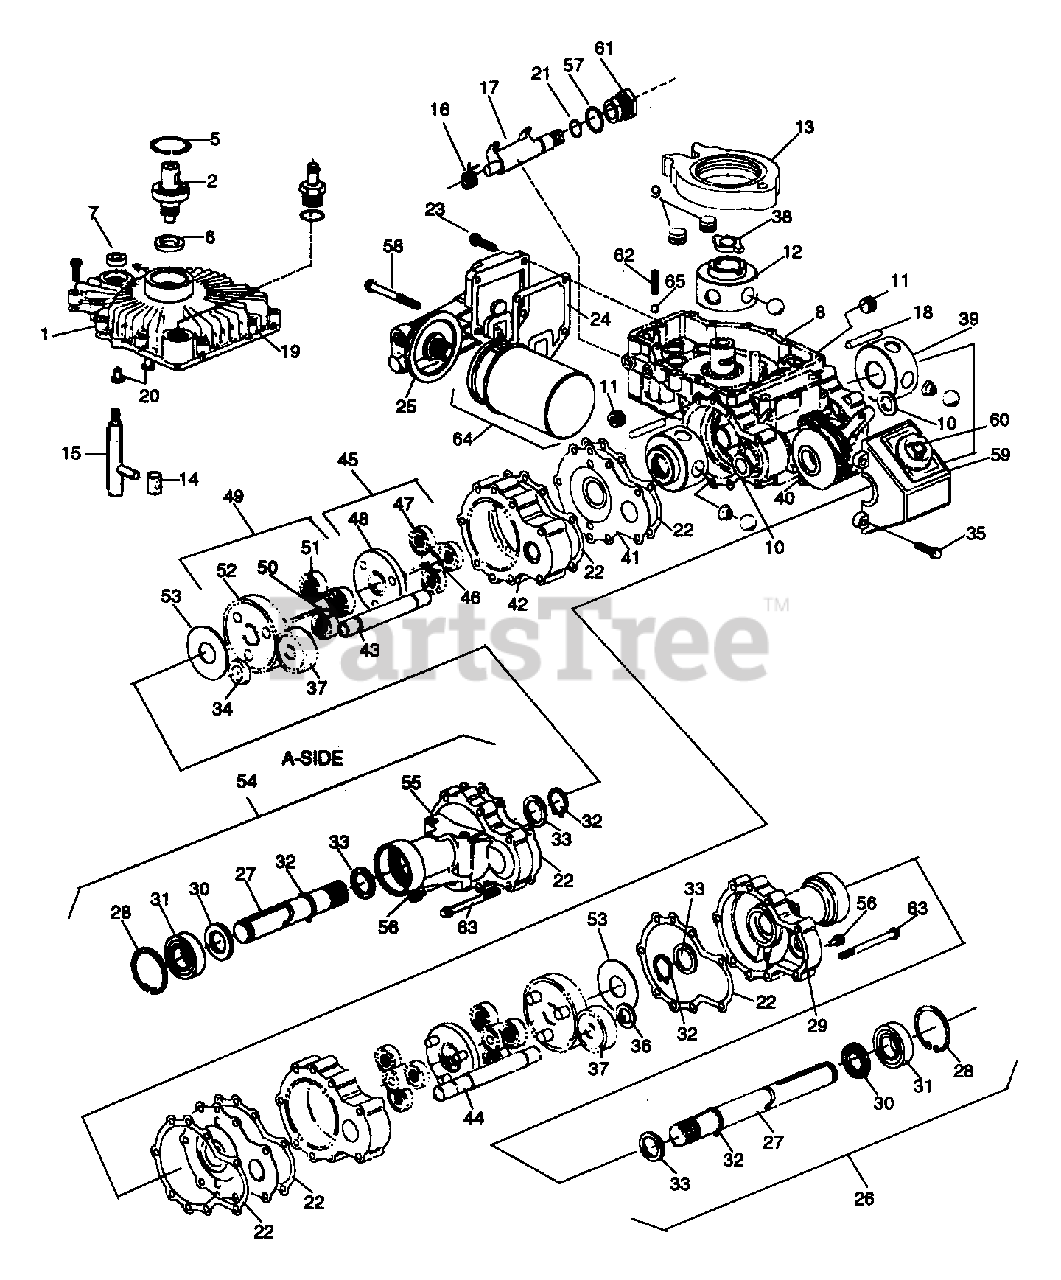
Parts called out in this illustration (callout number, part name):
1	COVER, SUBASSEMBLY
2	INPUT SHAFT SUBASSEMBLY
5	RING RETAINING, INT
6	SEAL, INPUT SHAFT
7	SEAL, CONTROL SHAFT
8	HOUSING SUBASSEMBLY
9	PISTON, DAMPENING SUBASSEMBLY
10	SEAL, BRAKE SHAFT
11	.625 RT ANGLE FITTING/O-RING
12	PUMP, ROTOR-BALL-PIN S/A
13	CAM RING S/A
15	CONTROL SHAFT SUBASSEMBLY
16	SPRING, DUMP VALVE
17	BRACKET, DUMP VALVE
19	GASKET, COVER
21	O-RING, DUMP VALVE BRACKET
22	GASKET, AXLE HOUSING
23	SCREW, 1/4 -20 HEX FLANGE
24	GASKET, FILTER BASE
25	FILTER BASE S/A
26	AXLE HOUSING, S/A - B
27	SHAFT, AXLE - A&B
28	RETAINING RING, INT.
29	HOUSING, AXLE - B
30	SEAL, AXLE SHAFT
31	BEARING, AXLE SHAFT
32	RETAINING RING, EXT. - B
33	WASHER, THRUST
34	AXLE HOUSING SUBASSEMBLY - A
35	SCREW, 1/4-20 SELF TAP
36	AXLE HOUSING SUBASSEMBLY - B
37	BRAKE GEAR
39	15T MOTOR, ROTOR-BALL S/A
40	BRAKE ASSEMBLY - 50 DEGREE
41	PLATE, WEAR
42	57T RING GEAR S/A
43	BRAKE SHAFT - A
44	BRAKE SHAFT - B
45	PLANETARY GEAR, FITST S/A
46	15T SUN GEAR, FIRST
47	21T PLANET GEAR, FIRST S/A
48	15T PRIMARY CRARIER S/A
49	PLANETARY GEAR, SECOND S/A
50	15T SUN GEAR, SECOND
51	21T PLANET GEAR, SEC. S/A
52	SECONDARY CARRIER, S/A 18T
53	AXLE HOUSING SUBASSEMBLY - A
54	AXLE HOUSING, S/A-A
55	HOUSING, AXLE - A
56	PLUG MAGNETIC
58	SCREW, 1/4-20 HEX FLG.
59	COVER, BRAKE
60	DUST BOOT
61	DUMP VALVE NUT
62	SPRING, RELIEF VALVE
63	SCREW, 1/4-20 HEX FLANGE
64	FILTER, OIL (WISEAL)
65	BALL, GRADE 200
